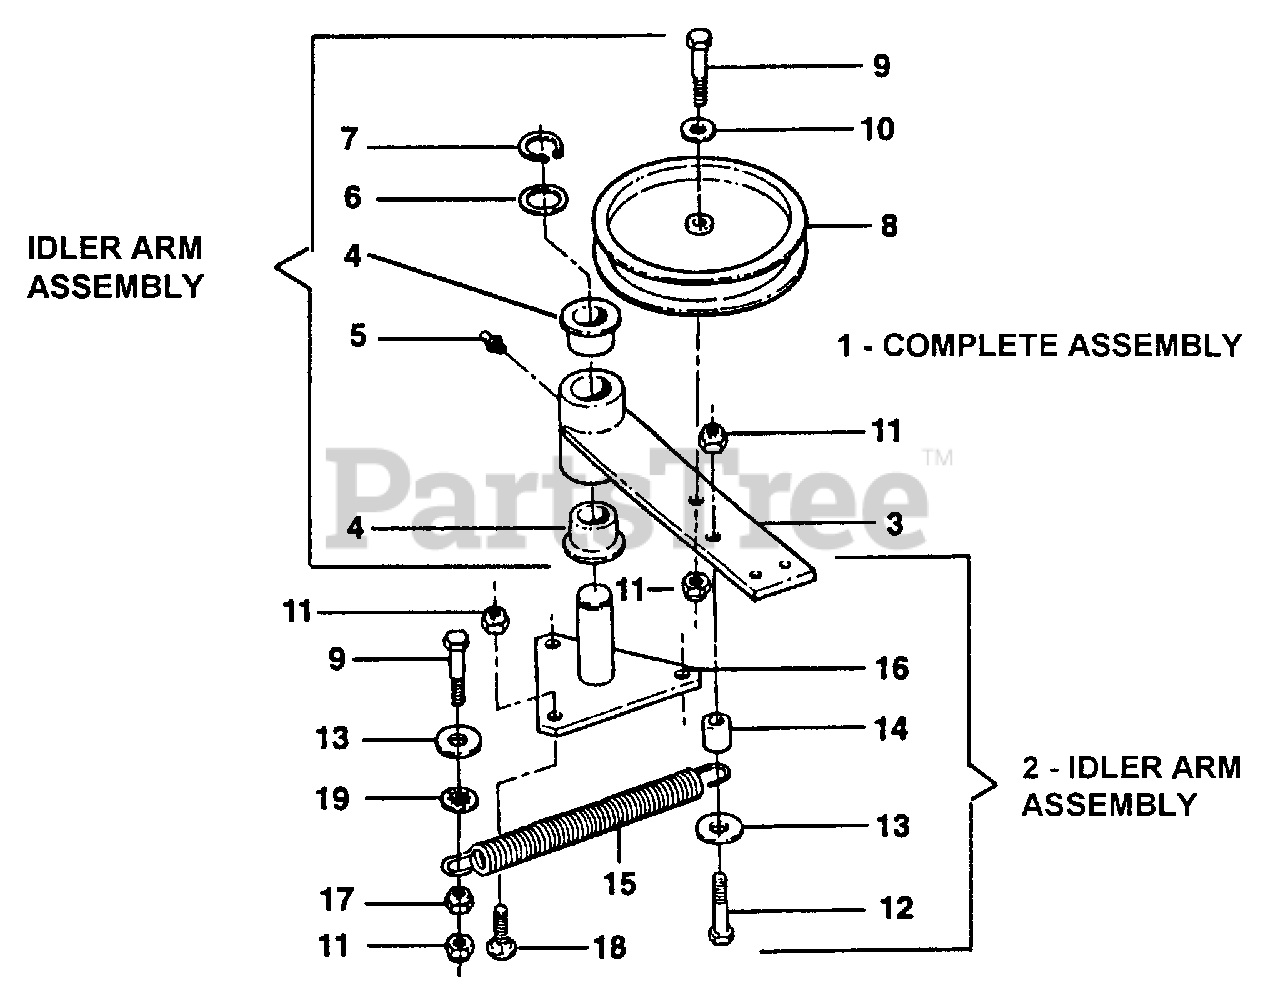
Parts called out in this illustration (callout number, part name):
1	ASSEMBLY, Spring-Loaded Idler Group
2	ASSEMBLY, Idler Arm
3	ARM, Idler (Weldment)
4	BUSHING
5	FITTING, 1/4-28 Straight
6	WASHER, 1.031 x 1.25 x .03" Flat
7	E-RING, 1"
8	PULLEY, 5 1/2" O.D.
9	BOLT, 3/8-16 X 2, GD5, CZ
10	WASHER, 3/8" USS
11	NUT, 3/8-16 HEX NYLON LOCK
12	SCREW, 3/8-16 x 1 3/4" Hex Head Cap, Grade 5
13	WASHER, .406 x 1.5 x .120" (YZ)
14	SPACER, .50 I.D. x .75 O.D. x 83"
15	SPRING, Extension
16	PIVOT, Idler (Weldment)
17	NUT, 3/8-16 HEX SERRATED FLANGE
18	BOLT, 3/8-16 x 1" Carriage
19	RETAINER, 3/8" Bolt
